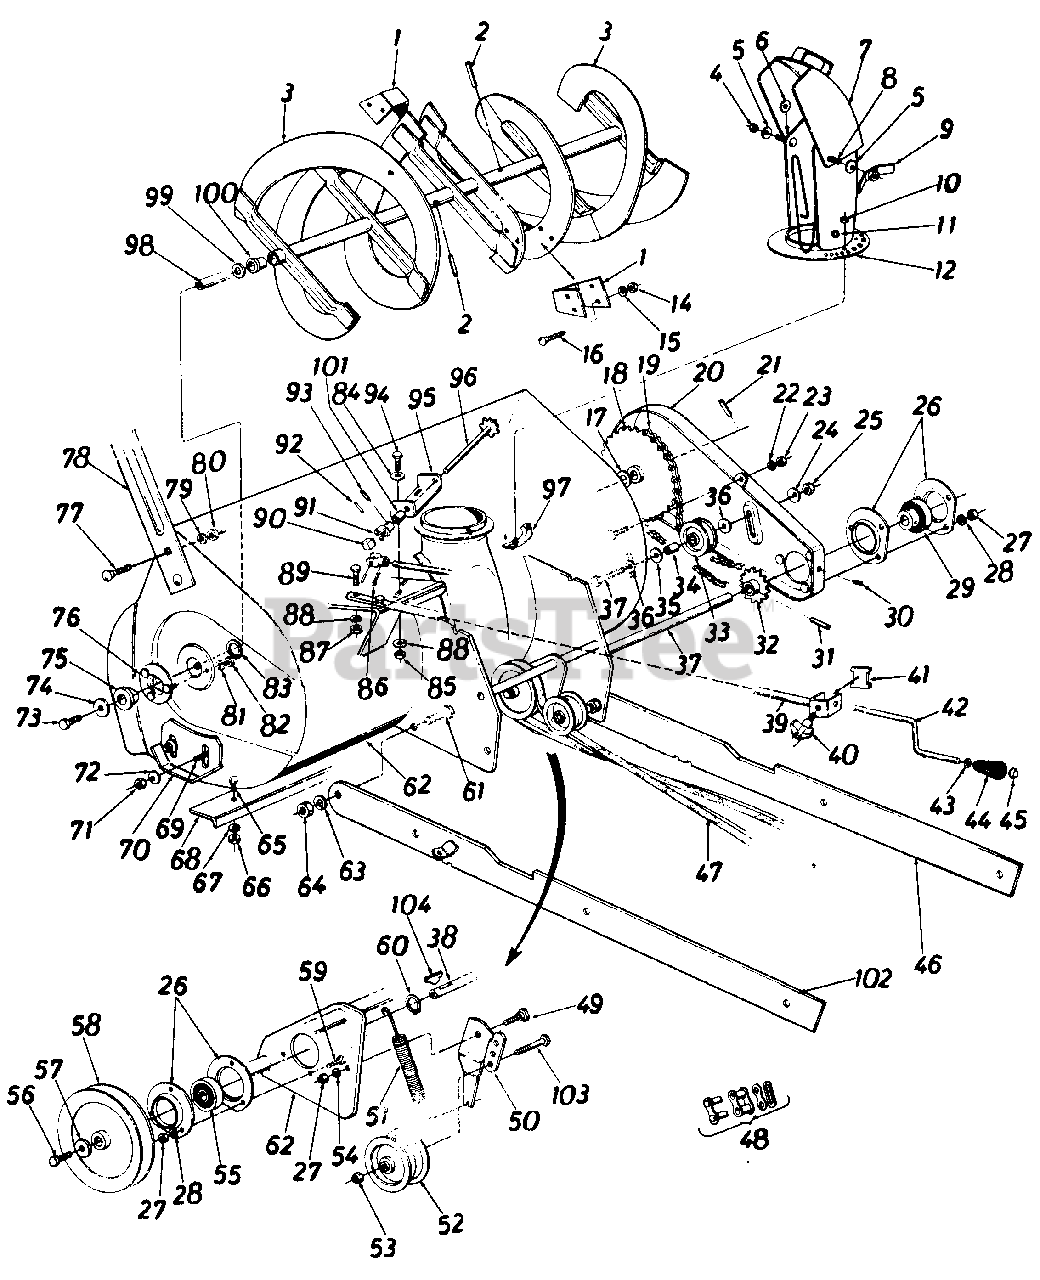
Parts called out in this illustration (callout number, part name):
1	Spiral Plate
2	Spring Pin Spir. 5/16 x 1.75" Lg.
3	Spiral Ass'y.
4	Hex Cent. L-Nut 5/16-18 Thd.
5	Bell. Wash.
6	Fl-Wash.
7	Top Chute Ass'y.
8	Car. Bolt 5/16-18 x .62" Lg.
9	ChuteWing Ass'y.
10	Hex Cent. L-Nut 1/4-20 Thd.
11	Push Cap.188" Dia. Rod
12	Chute Ass'y.
14	Hex Nut 5/16-18 Thd.*
15	L-Wash. 5/16" Scr.*
16	Car. Bolt 5/16-18x.62" Lg.*
17	Fl-Wash.
18	Sprocket Hub Ass'y.-40 Teeth
19	#420Chainx 1/2" Pitch-77 Links
20	Chain Guard Ass'y.
21	Spring Pin Spir. - 5/16
22	L-Wash. 5/16" Scr.*
23	Hex Nut 5/16-18 Thd.*
24	Bell. Wash.
25	Hex Ins. L-Nut 3/8-16 Thd.
26	Bearing Housing
27	Hex Nut 5/16-18 Thd.*
28	L-Wash. 5/16" Scr.*
29	Self Aligning Brg. w/Set Scr.
31	Spring Pin Spir. - 5/16x 1.75
32	14 Teeth Sprocket Ass'y.
33	1.875" Dia. Flat Idler
34	Idler Spacer
35	F l-Wash .
36	Fl-Wash.
37	Hex Scr. 3/8-16x 2.00" Lg.*
38	Drive Shaft
39	Crank Support Tubing Ass'y.
40	Hand Knob 5/16-18 Thd.
41	Chute Crank Brkt.
42	Chute Crank
43	Fl-Wash .
44	Knob-Black 3/8" Dia. Hole
45	Push Nut 3/8" Rod
46	Linkage Arm Ass'y.
47	"V"-Belt 1/2"x85" Lg. (Kevlar)
48	Master Link for #420 Chain
49	Shoulder Scr.
50	Idler Brkt. Ass'y.
51	Extension Spling
52	Fl. Idlerwith Flange
53	Hex Ins. Jam Nut 3/8-16 Thd.
54	L-Wash. 5/16" Scr.*
55	Self Aligning Brg.
56	Hex Scr. 5/16-18x.62" Lg.
57	Fl-Wash.
58	5.50 O.D. x 5/8 Pulley
59	Hex Sems Scr. 5/16-18 x .75"
60	Snap Ring for.75 Dia. Shaft
61	Hex Scr. 1/2-13 x 1.25" Lg.*
62	Spiral Housing Ass'y.
63	L-Wash. 1/2" Scr.*
64	Hex Nut 1/2-13 Thd.*
65	Car. Bolt 5/16-18 x .62" Lg.*
66	Hex Nut 5/16-18 Thd.*
67	L-Wash. 5/16" Scr.*
69	Car.Bolt 3/8-16x.75" Lg.*
72	Bell. Wash.
73	Hex Scr. 5/16-18x.62" Lg.
74	Fl-Wash.
75	Flange Brg. with Flats
76	Brg. Housing Ass'y.
77	Car. Bolt 5/16-18 x .62" Lg.
78	Guide Blade
79	L-Wash. 5/16" Scr.*
80	Hex Nut 5/16-18 Thd.*
81	L-Wash. 5/16" Scr.*
82	Hex Nut 5/16-18 Thd.*
83	Snap Ring for 1.50" Dia. Shaft
84	Bell. Wash.
85	Hex Nut 5/16-18 Thd.*
86	Cotter Pin 3/32 x 1 .00" Lg.*
87	Hex Nut 5/16-18 Thd.*
88	L-Wash. 5/16" Scr.*
89	Hex Scr. 5/16-18 x 1.50" Lg.
90	Joint Block
91	Joint Brkt. Ass'y.
92	Spring Pin Roll 3/16" x .81 " Lg.*
93	Spring Pin Roll 1/8 x .75" Lg.*
94	Hex Scr. 5/16-18 x .75" Lg.*
95	Chute Brkt.
96	Sprocket Shaft Ass'y.
97	Chute Flange Keeper Ass'y.
98	Spiral Axle
99	Fl-Wash.
100	Plastic Bushing
101	Spacer .380 I.D. x.630 O.D. x .565
102	Linkage Arm Ass'y. - R.H.
103	Hex Bolt 3/8-16 x 1.75" Lg.*
104	#61 Hi-Pro Key
